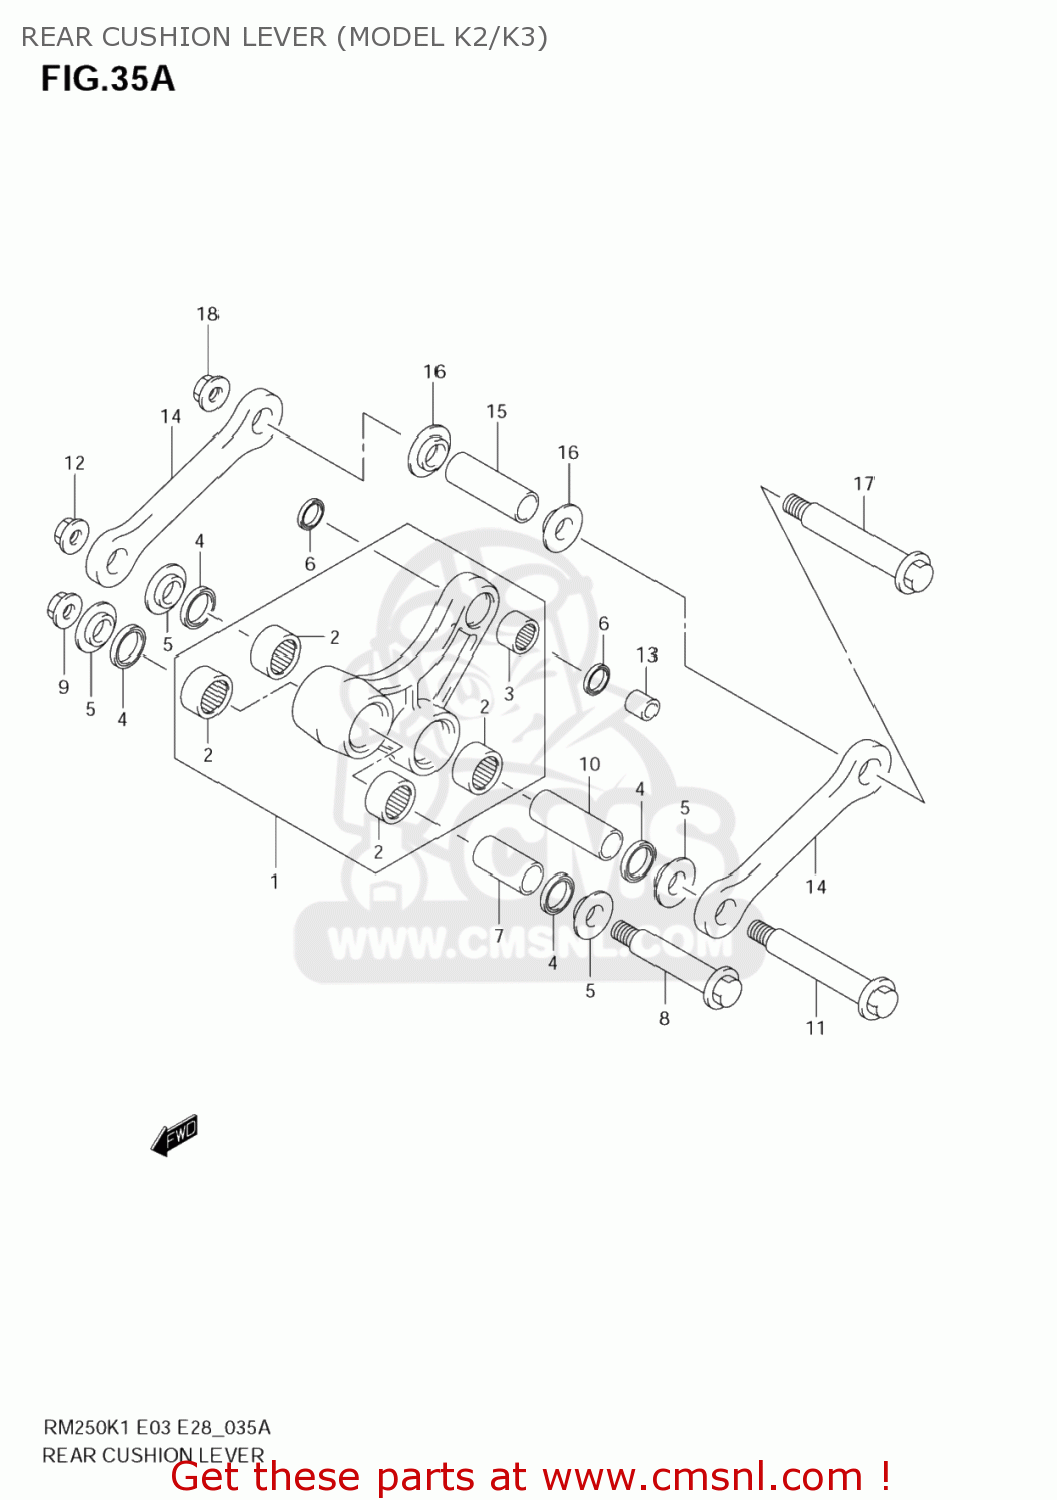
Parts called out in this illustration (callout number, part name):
1	LEVER SET,REAR
2	BEARING(20X27X15)
3	BEARING(20X26X12)
4	SEAL,CUSHION LEVER DUST
5	SPACER,RR CUSH ROD SIDE
6	SEAL,OIL(20X26X4.5)
7	SPACER,RR CUSHION LEVER FR
8	BOLT,RR CUSHION LEVER FR
9	NUT
10	SPACER,RR CUSHION
11	BOLT,RR CUSHION
12	NUT
13	SPACER,RR CUSHION LEVER RR
14	ROD,RR CUSHION
15	SPACER,RR CUSHION
16	SPACER,RR CUSH ROD SIDE
17	BOLT,RR CUSHION
18	NUT
